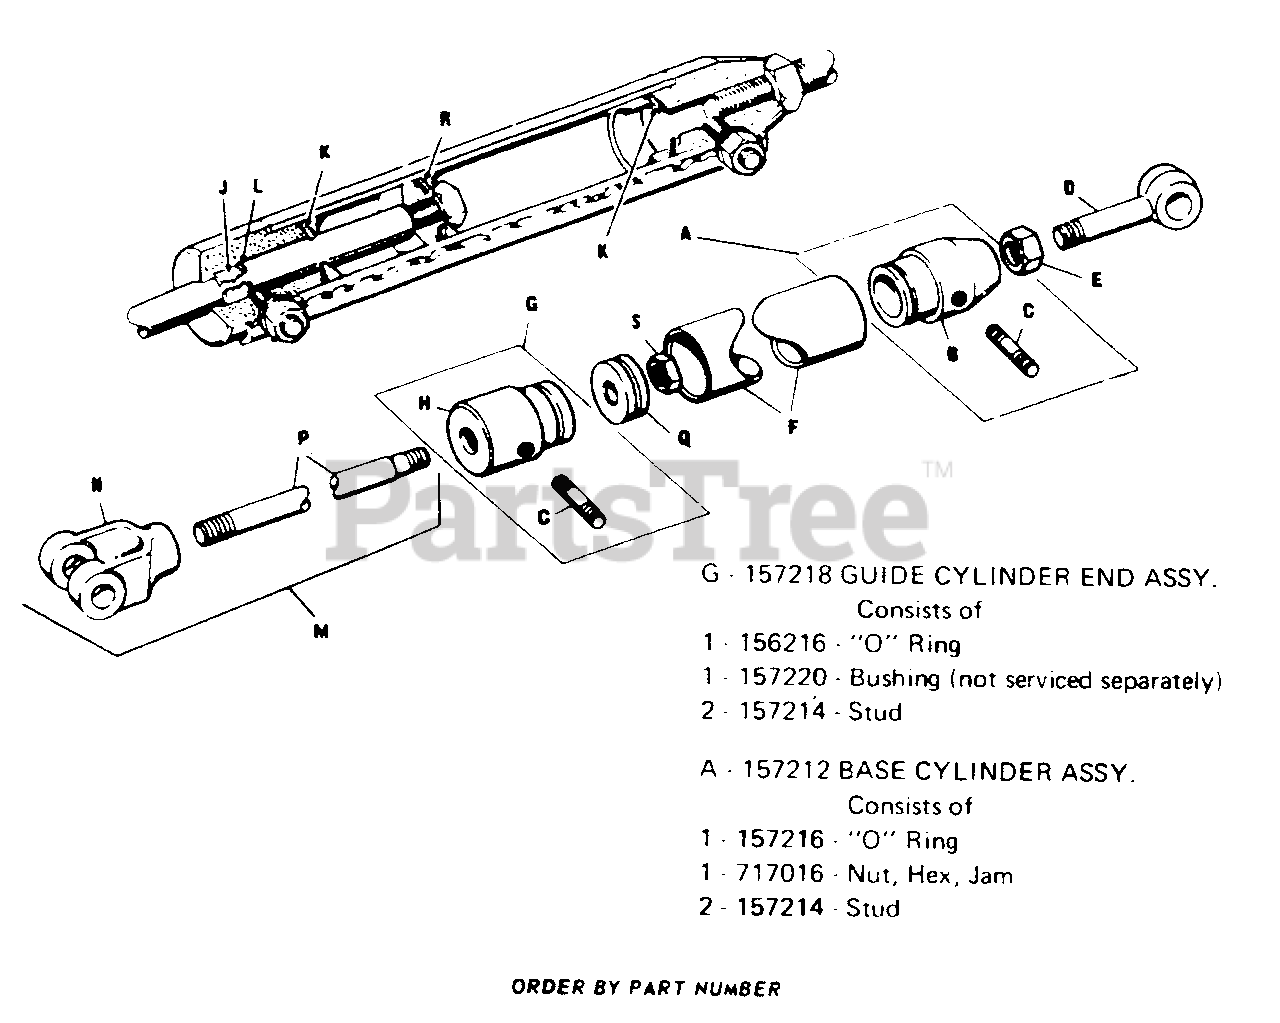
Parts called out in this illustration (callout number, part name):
A	Cylinder Base Sub-Assembly
B	Cylinder Base
C	Stud Bolt, 5/16"-18 x 7/8"
E	Jam Hex. Nut, 1/2"-20
G	Sub Assembly Guide
H	Cylinder End Guide
M	Yoke & Rod Sub-Assembly
P	Piston Rod
S	Full Hex. Nut
